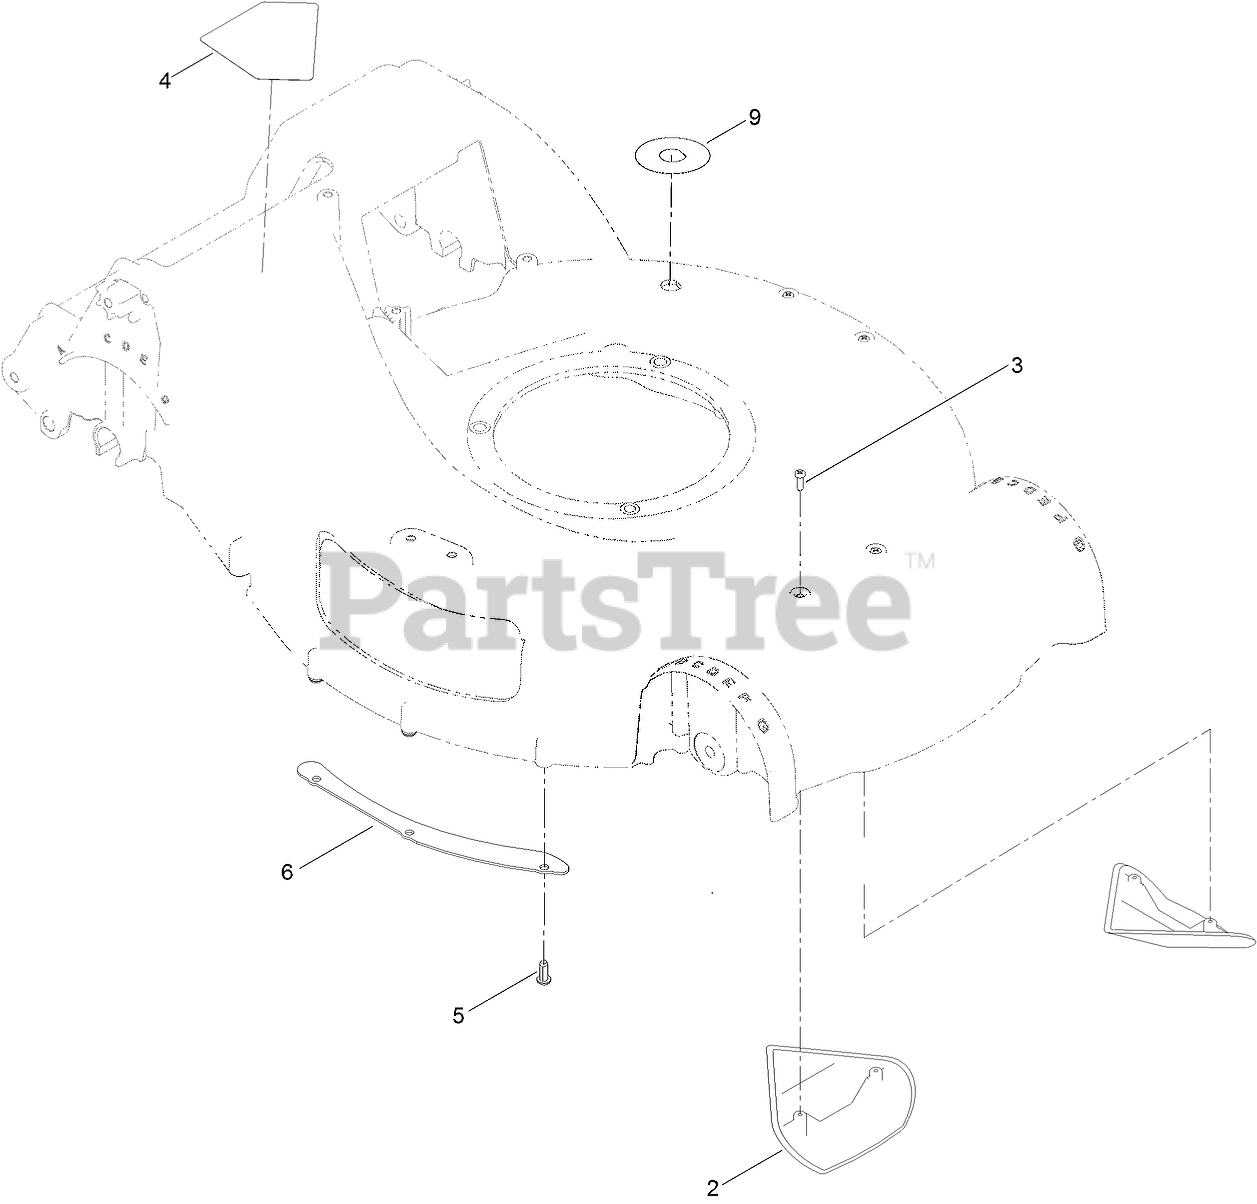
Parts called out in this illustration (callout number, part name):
2	KICKER-HOUSING
3	SCREW-PPH
4	DECAL-DANGER
5	SCREW
6	SHEET-LIP
9	DECAL-QUICK WASH
